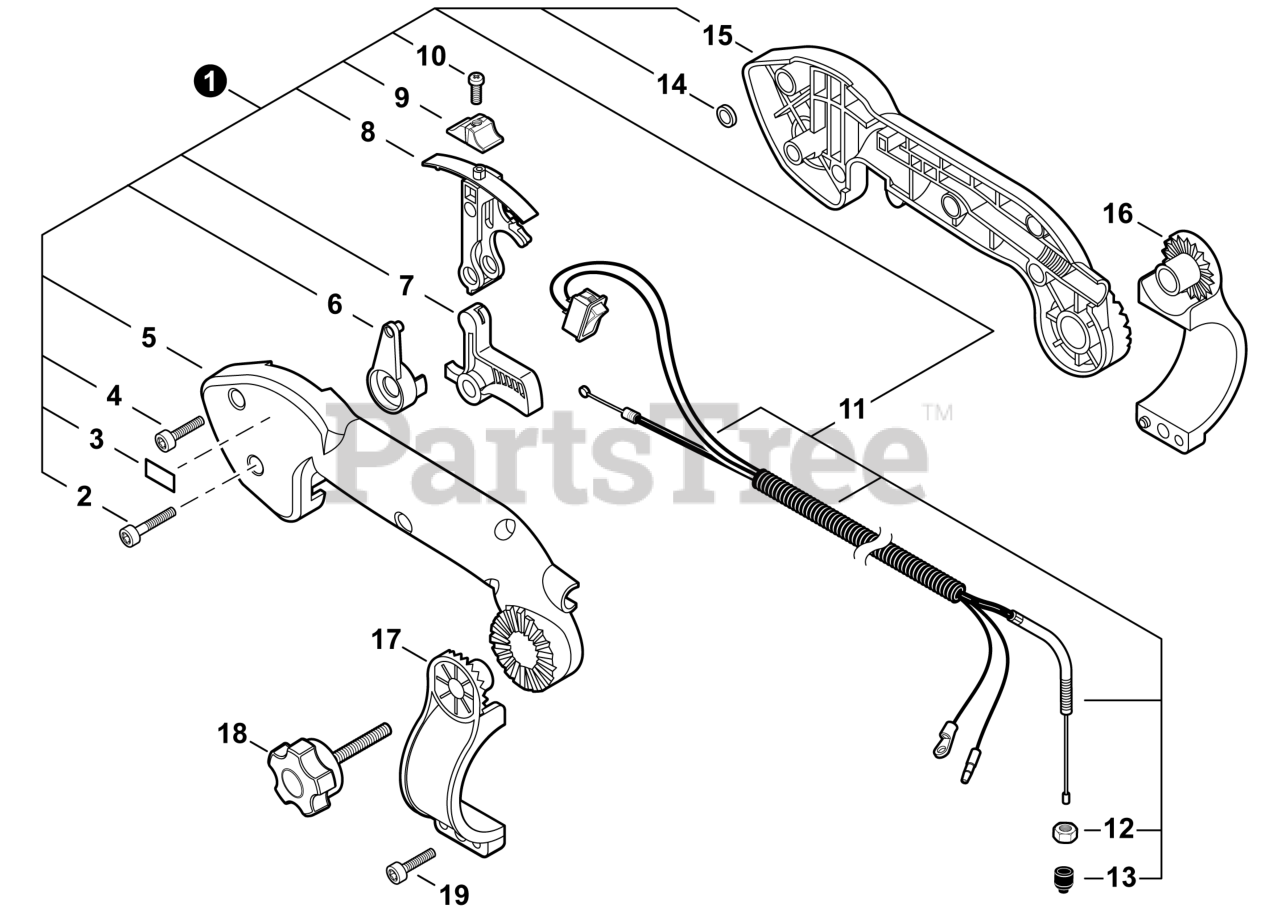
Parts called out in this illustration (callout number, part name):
1	THROTTLE CONTROL KIT - TUBE MOUNT
2	BOLT, TORX 5x25
3	LABEL - CAUTION - IDLE
4	BOLT, TORX 5x20
5	CONTROL HANDLE - LEFT
6	LEVER, THROTTLE
7	TRIGGER, THROTTLE
8	CONTROL, THROTTLE
9	KNOB, CONTROL
10	SCREW 3x14
11	CABLE ASSY, CONTROL
12	NUT, HEX M6
13	CAP, DUST
14	WASHER 5.2x8x0.5
15	CONTROL HANDLE - RIGHT
16	BRACKET, RIGHT
17	BRACKET, LEFT
18	KNOB, SCREW
19	BOLT, TORX 5x20
